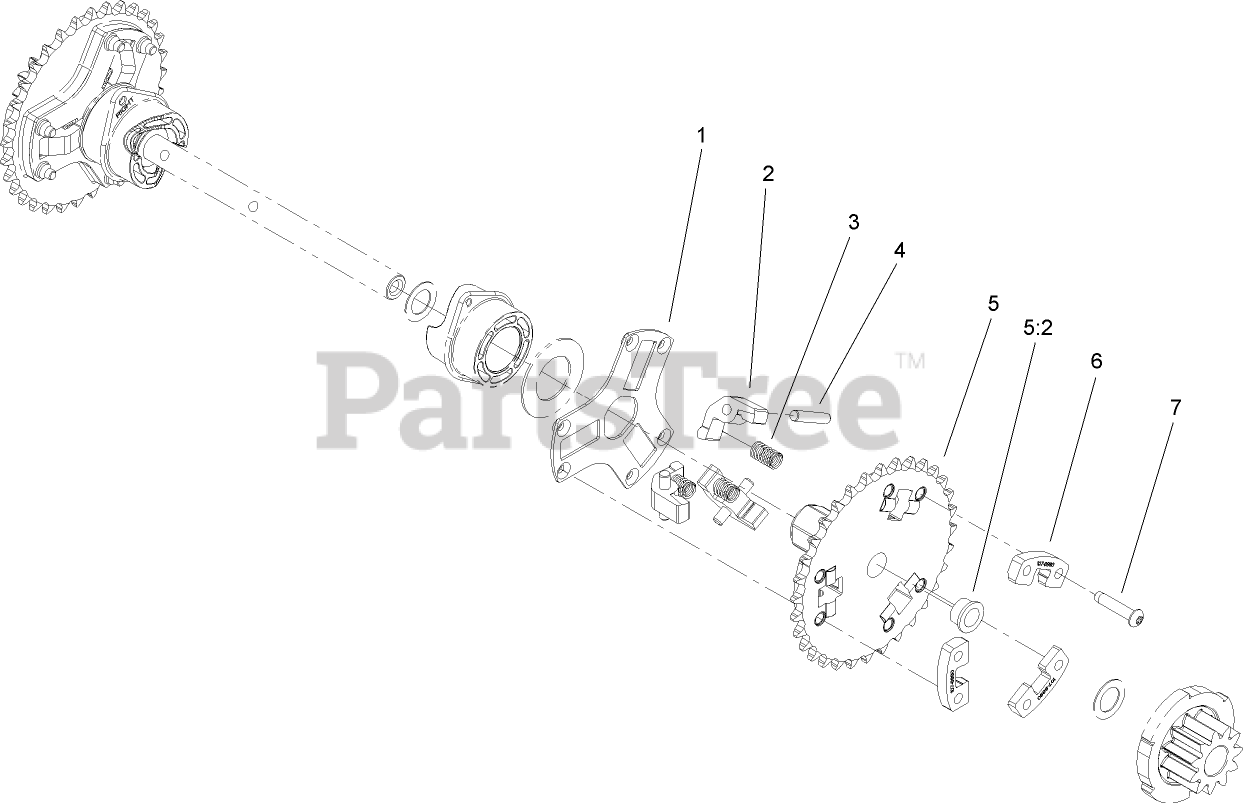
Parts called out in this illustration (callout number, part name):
1	RETAINER-PIN, PAWL
2	PAWL-CLUTCH
3	SPRING-COMPRESSION
4	PIN-DOWEL
5	32T SPROCKET ASM
5:2	BUSHING-FLANGE
6	SUPPORT-PAWL
7	SCREW-TTH, THREAD ROLLING
